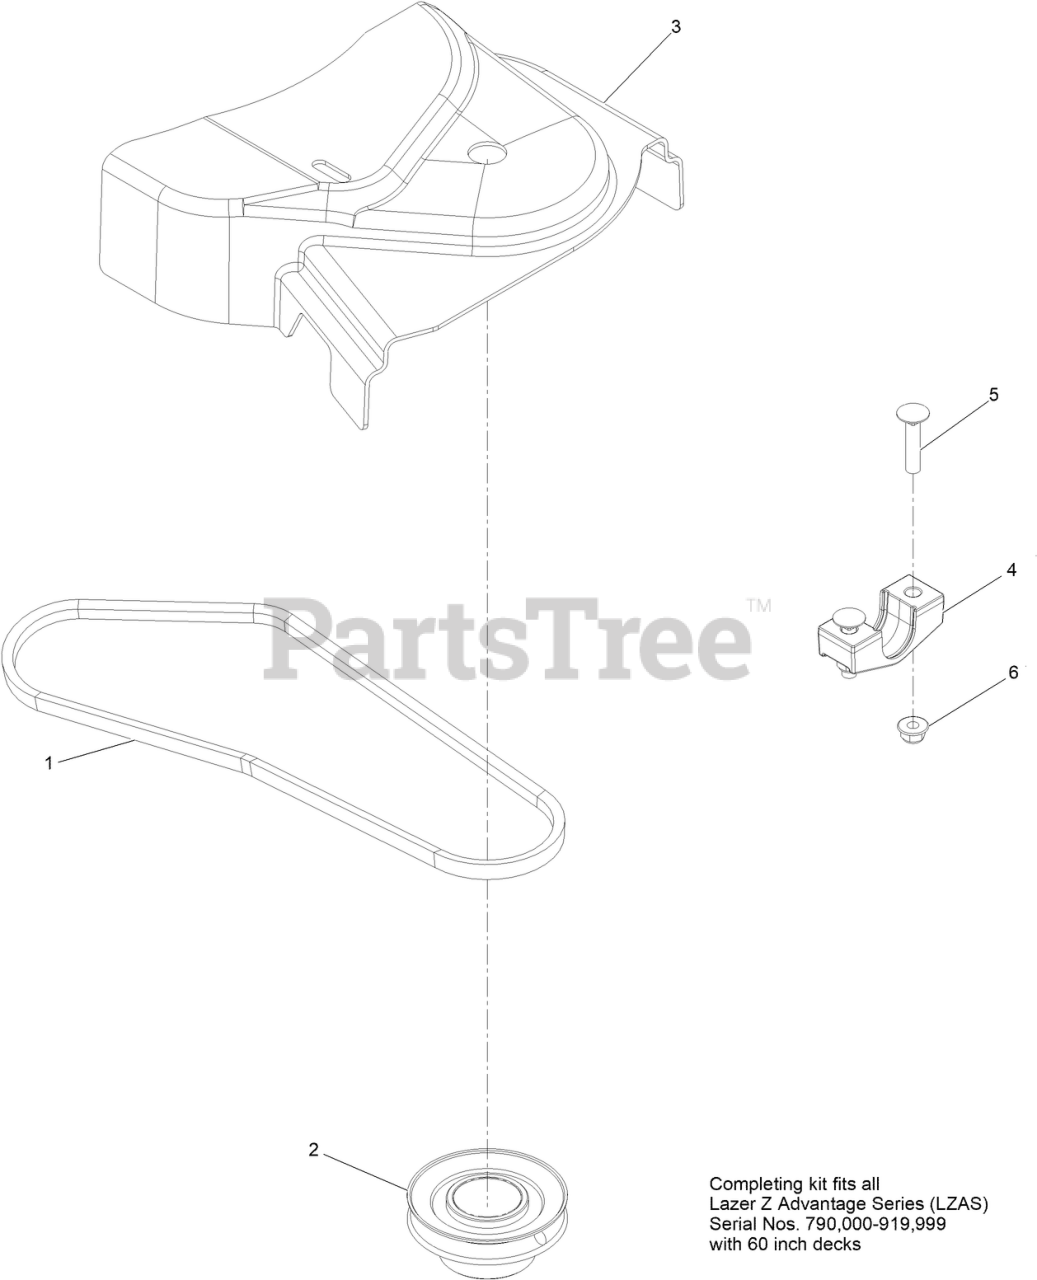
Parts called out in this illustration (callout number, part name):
2	SHEAVE,DRIVE LZUV 526
3	COVER,BELT UV 52
4	SUPPORT-BEARING CROSS SHAFT
5	SCREW-CARR
6	NUT-HF, NI
